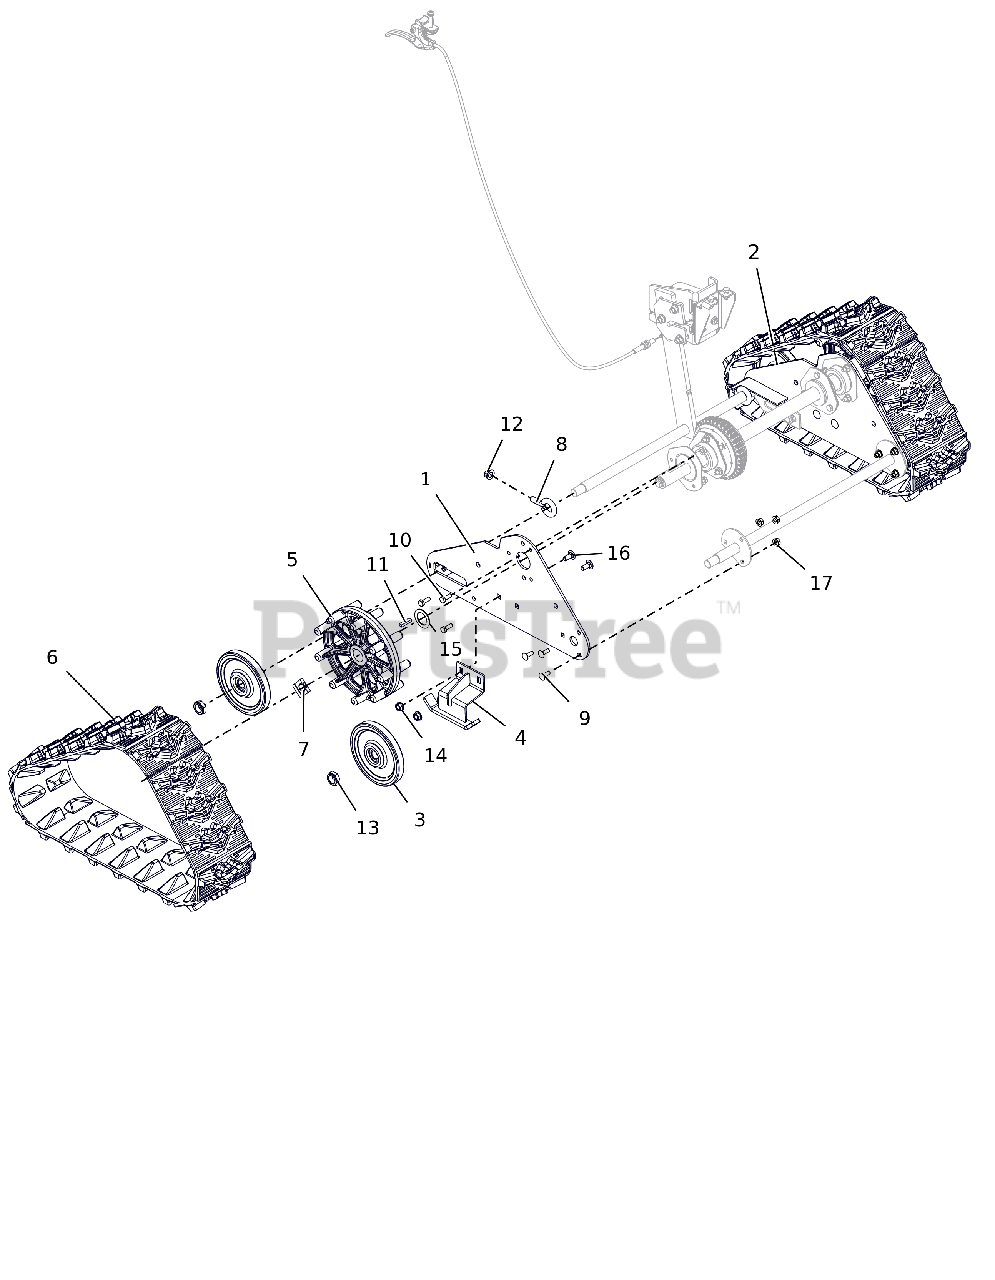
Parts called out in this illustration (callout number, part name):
1	SIDE PLATE, RH-TRACK
2	SIDE PLATE, LH-TRACK
3	WHEEL, BOGIE - SINGLE BEARING
4	RUNNER, GUIDE-TRACK
5	WHEEL, MACHINED DRIVE
6	TRACK, RUBBER
7	CLIP, SNAP .625 DIA
8	BLT-EYE .375-16X.880 YWZC
9	@BLT-RDHDSQNK .25-20X.75 G5YZ
10	@BLT-HEX .25-20X.75 GR5 YWZC
11	KEY-RECT .25X.188X1.00
12	NUT-LK-CTR-FLG .38-16 YWZC
13	@NUT-LK-NYL .625-18 YWZC
14	@NUT-LK-TOP-FLG .31-18 YWZC
15	WSHR-FL-STL 1.010X1.505X.062YZ
16	@BLT-RDHDSQNK .31-18X.75 G5YZ
17	@NUT-LK-TOP-FLG .25-20 YWZC
